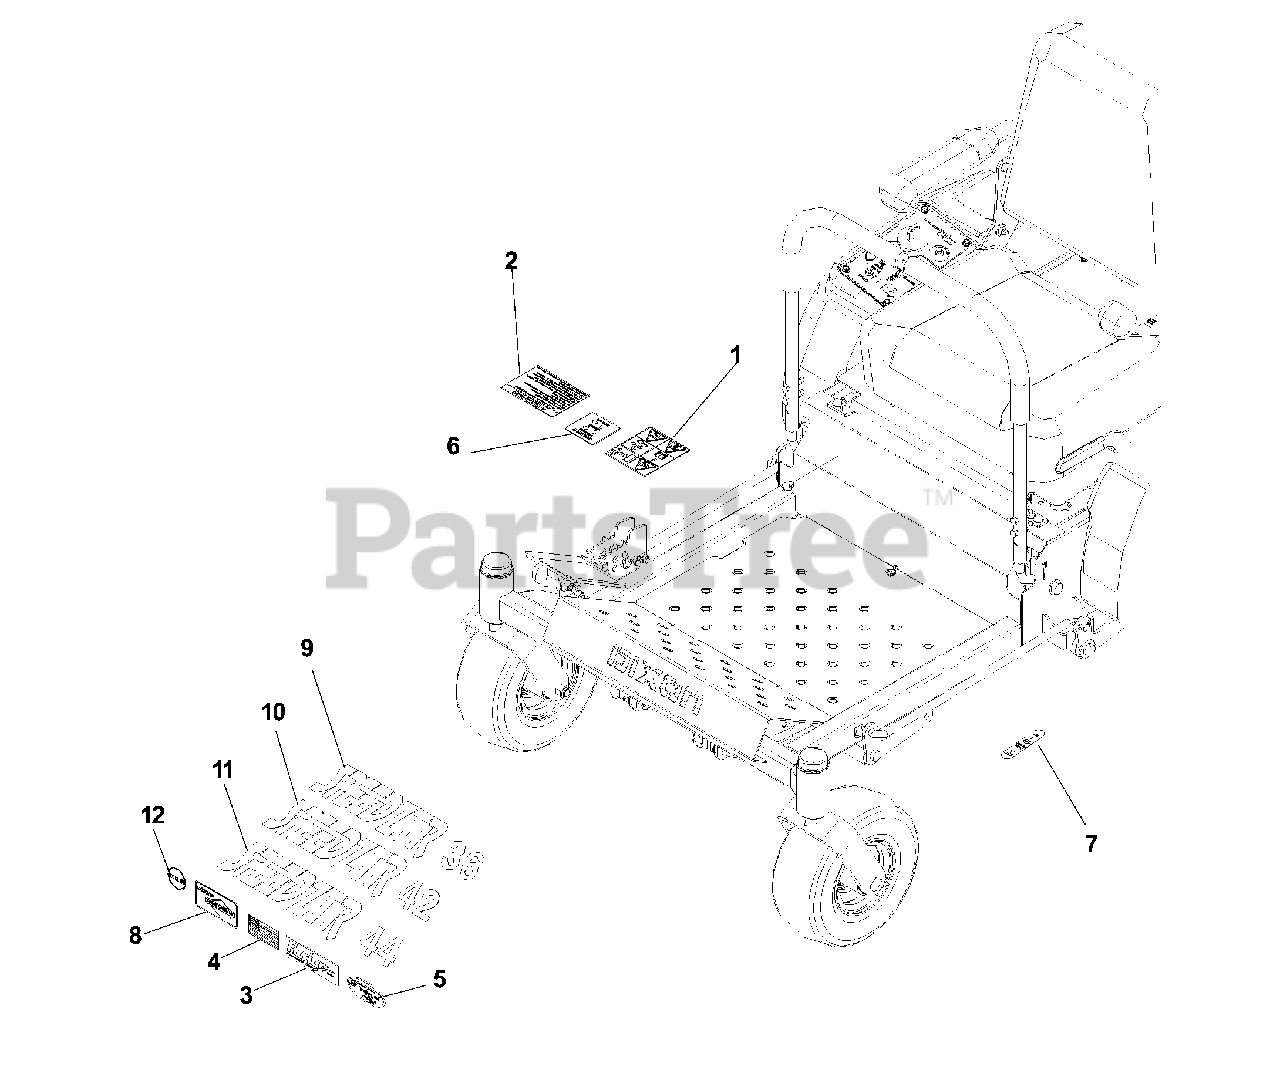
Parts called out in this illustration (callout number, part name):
1	DECAL, WARNING
2	DECAL, WARNING
3	DECAL, FUSION
4	DECAL, FLAG
5	HG DECAL(BLN-52241)
6	DECAL, DRIVE LEVERS
7	DECAL, PARK BRAKE
8	DECAL
11	DECAL, SPDZTR 44
